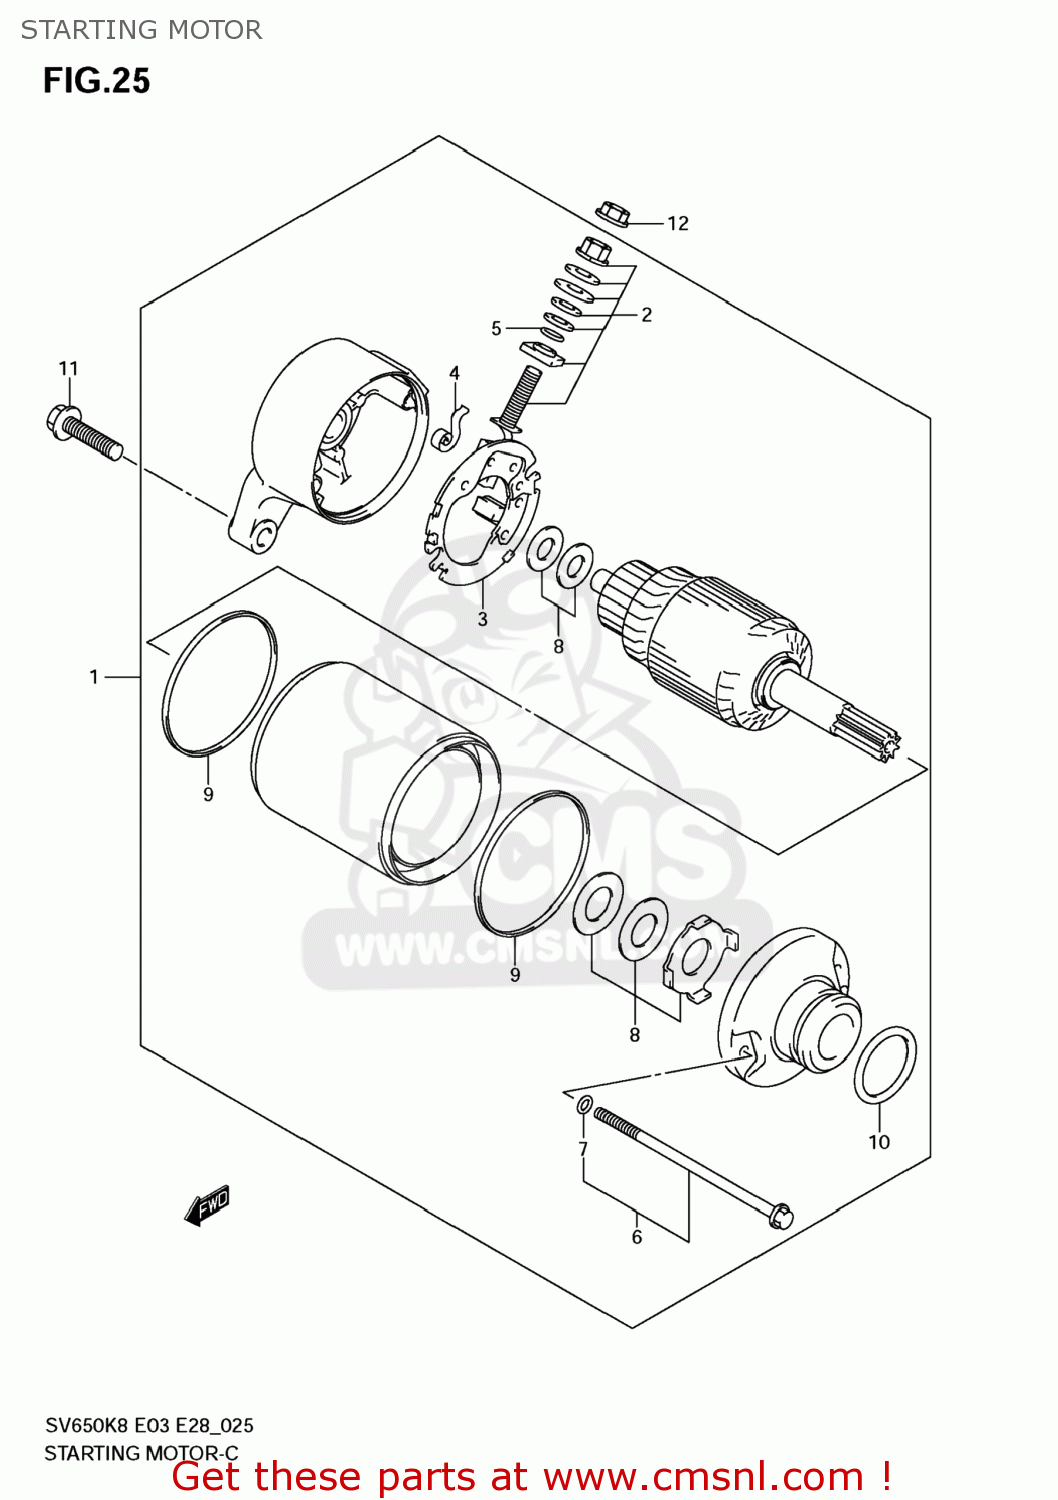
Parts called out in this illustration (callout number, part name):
1	MOTOR ASSEMBLY,STARTING
2	BRUSH TERMINAL SET
3	BRUSH HOLDER SET
4	SPRING,BRUSH
5	O RING
6	BOLT SET
7	O RING
8	SHIM SET,STARTING MOTOR
9	O RING
10	O RING(D:3,ID:24.5)
11	BOLT(6X25)
12	NUT
